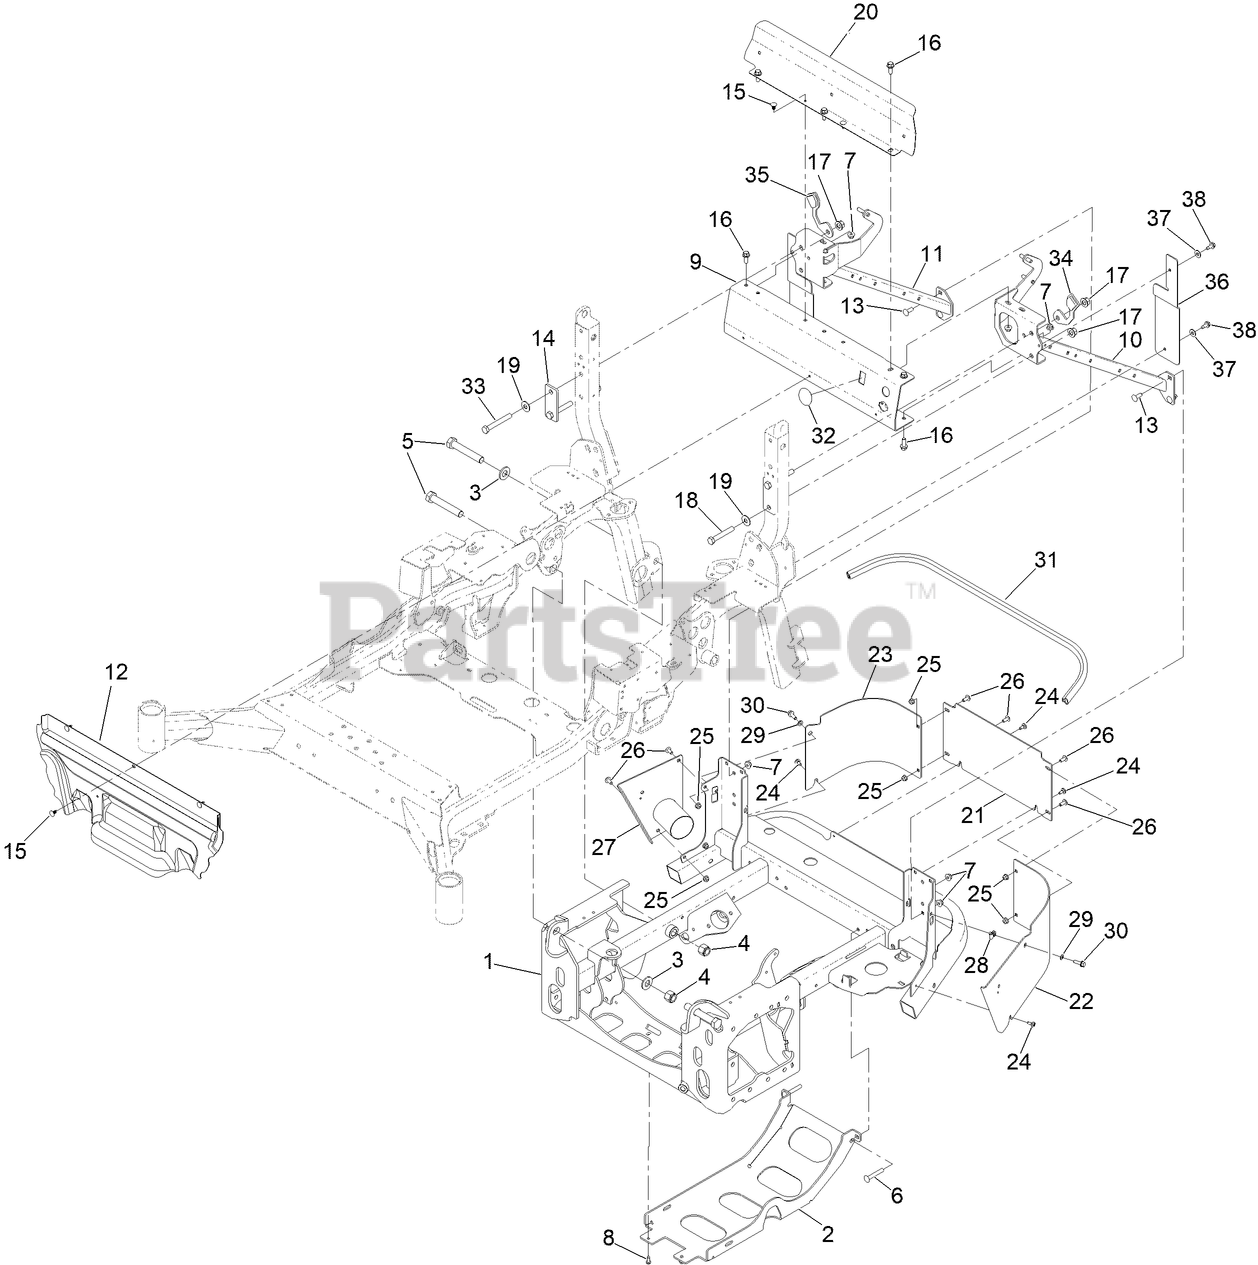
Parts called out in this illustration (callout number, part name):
1	FRAME-POWER
2	PLATE-SKID
3	WASHER
4	NUT-LOCK, NI
5	SCREW-HH
6	SCREW-CARR
7	NUT-HF, NI
8	SCREW-BHTF
9	CHANNEL-CROSS
10	WLDMT-ROPS LH BRACE
11	WLDMT-ROPS RH BRACE
12	PANEL-DEFLECTOR, HEAT
13	SCREW-CARR
14	PLATE-SPACER
15	PLUG-PLASTIC
16	SCREW-HHF
17	NUT-LOCK
18	SCREW-HH
19	WASHER-SPRING
20	SHIELD-AIR
21	PLATE-BUMPER, CENTER
22	PLATE-BUMPER, LH
23	PLATE-BUMPER, RH
24	SCREW-SHOULDER
25	NUT-HF, NI
26	SCREW-TORX
27	PLATE-EXHAUST
29	WASHER-BELLEVILLE
30	SCREW-HHF
31	SEAL-BULB
32	DECAL-COVER
33	SCREW-HH
34	STOP-ROPS [BLACK]
35	STOP-ROPS [BLACK]
36	SHEET-ROPS AIRDAM
37	WASHER-FLAT
38	SCREW-HWHTF
